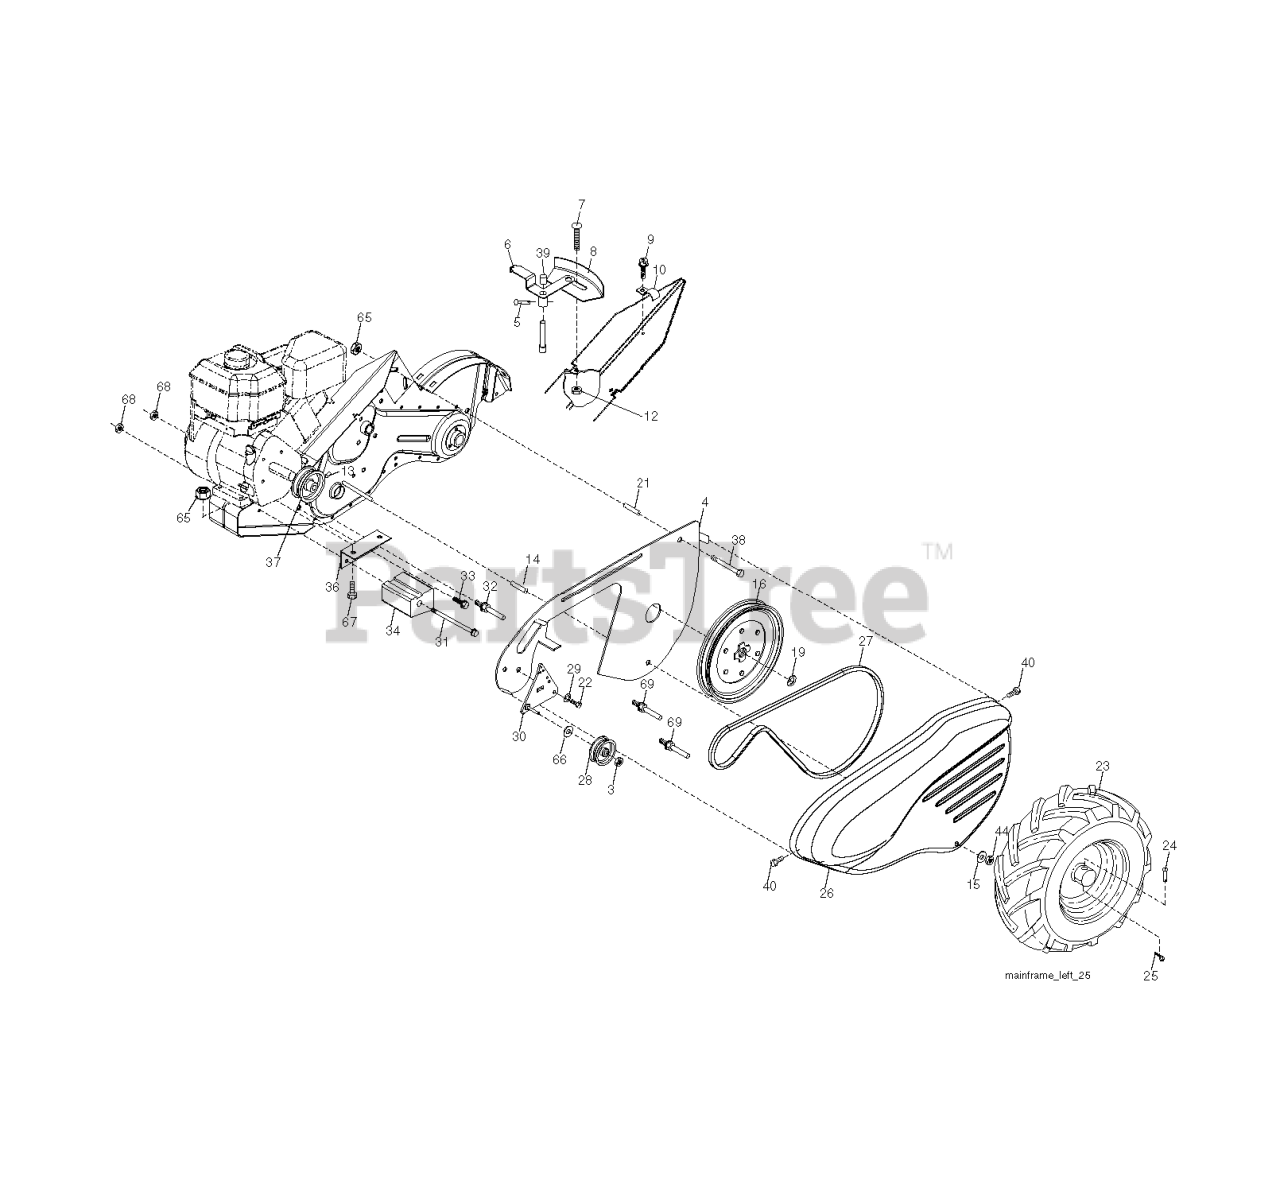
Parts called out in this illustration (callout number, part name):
3	LOCKNUT
4	SHIELD.INNER.BELT.GUARD.RT
5	PIN.SPIROL.FLARED
6	LEVER.ASM.SHIFT.RED
8	RP.PANEL.SHIFT
9	TAPPING SCREW
10	CONDUIT.CLIP.PLATED
12	NUT
14	SPACER CRT
15	WASHER
16	SHEAVE, TRANSMISSION
19	RETAINING RING LT
21	SPACER-SPLIT.327 X .42
23	TIRE.13X5-6.CHEVRON.TILLER
24	RIVET,DRILLED
25	RETAINER M
26	RP BELT GUARD
27	V-BELT
28	PULLEY-IDLER TI
30	BRACKET.ASM.IDLER.BLACK
31	BOLT.FIN.HEX.3/8-16UNC
32	SHIFT ARM CRT
33	BOLT
34	COUNTERWEIGHT.LH.CRT
36	BRACKET LH CRT
37	RP.ENGINE PULLEY
38	BOLT
39	CAP.PLUNGER.BLACK
40	SCREW.HEX.WSH.SLT.#10-24X.50
44	NUT.71038.31-18.HEX.NYLOCK
65	LOCKNUT-FLANGE 5/16-18
66	WASHER
67	BOLT, HEX 5/16-18X1-3/4
69	KEEPER.BELT.ENGINE
